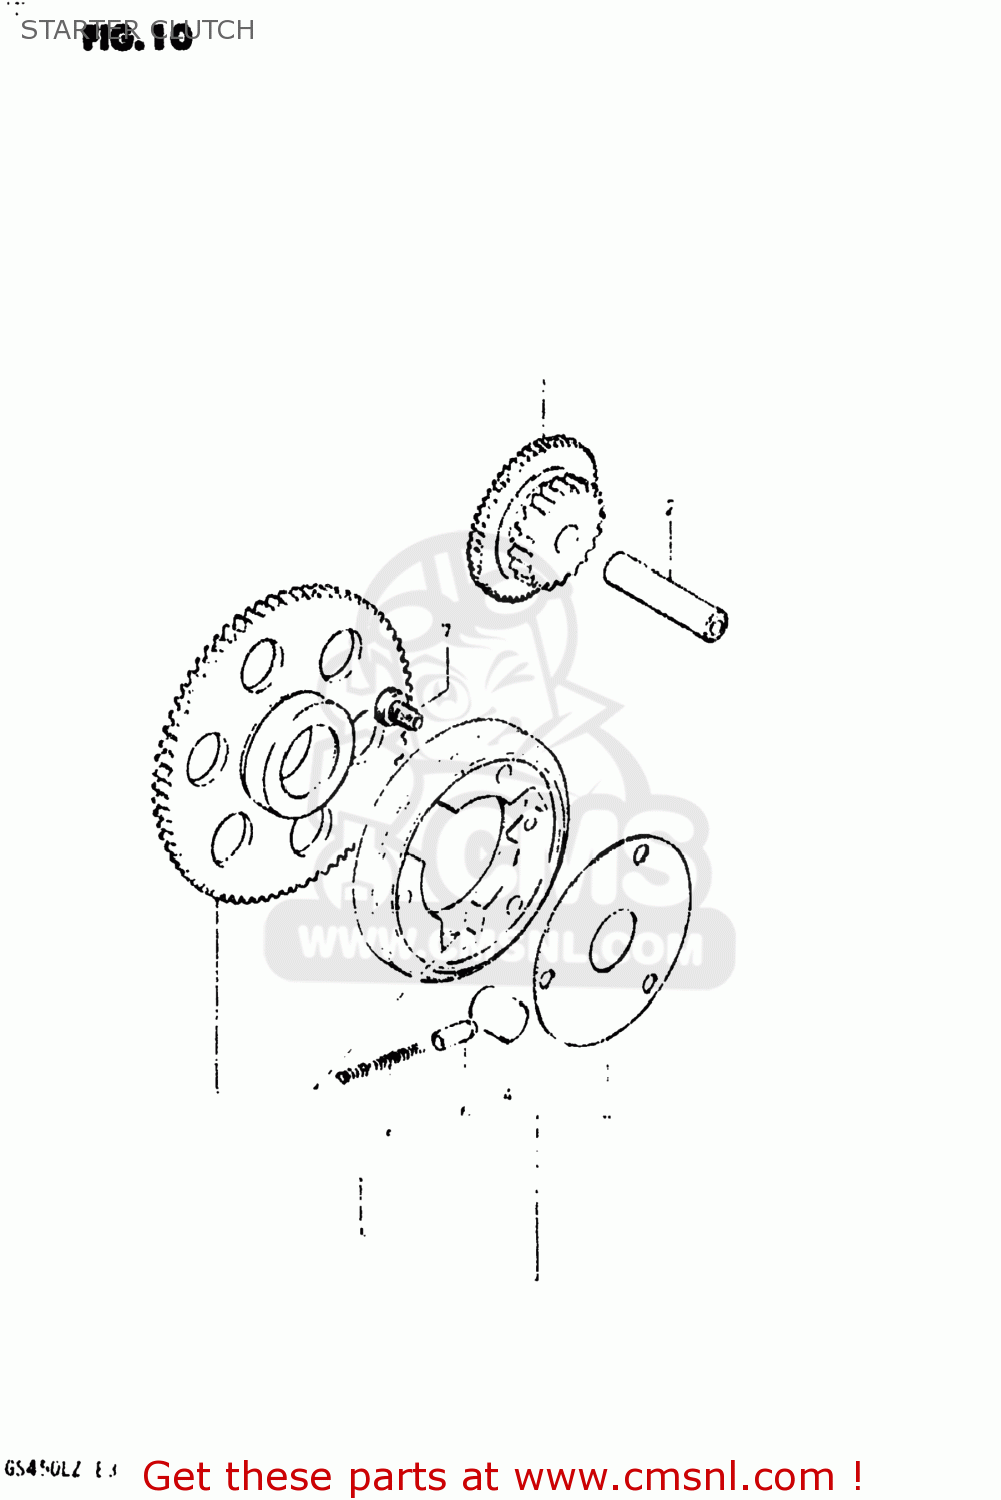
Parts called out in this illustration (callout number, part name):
1	GEAR,STARTER IDLE
2	PIN(7.4X13X56)
3	CLUTCH SET,STARTER
4	ROLLER(15X13)
5	SPRING
6	PIECE,PUSH
7	BOLT
8	SHIM,STARTER CLUTCH HUB
